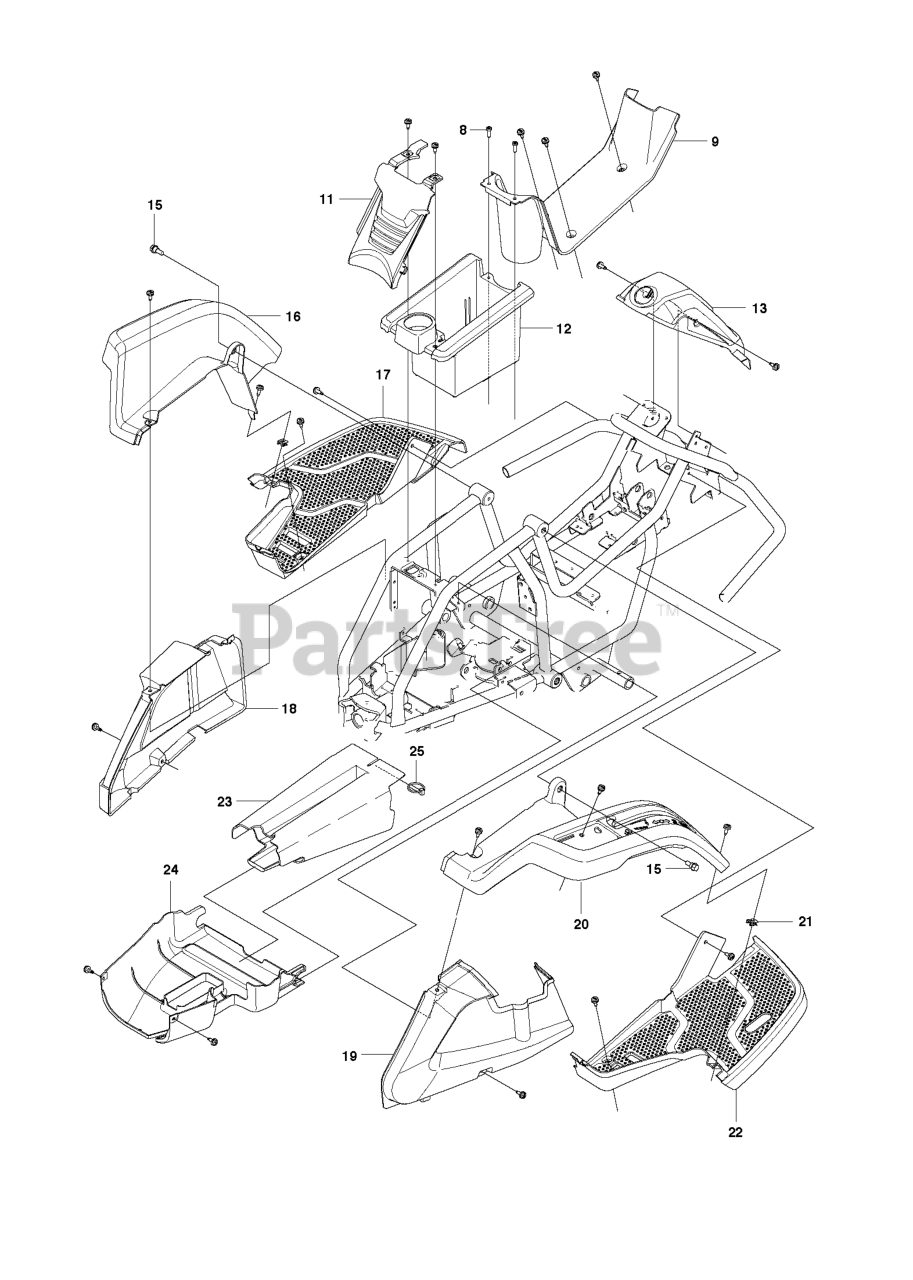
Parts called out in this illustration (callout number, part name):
12	BATTERY BOX
17	FOOT PLATE
20	CONTROL PANEL
22	FOOT PLATE
